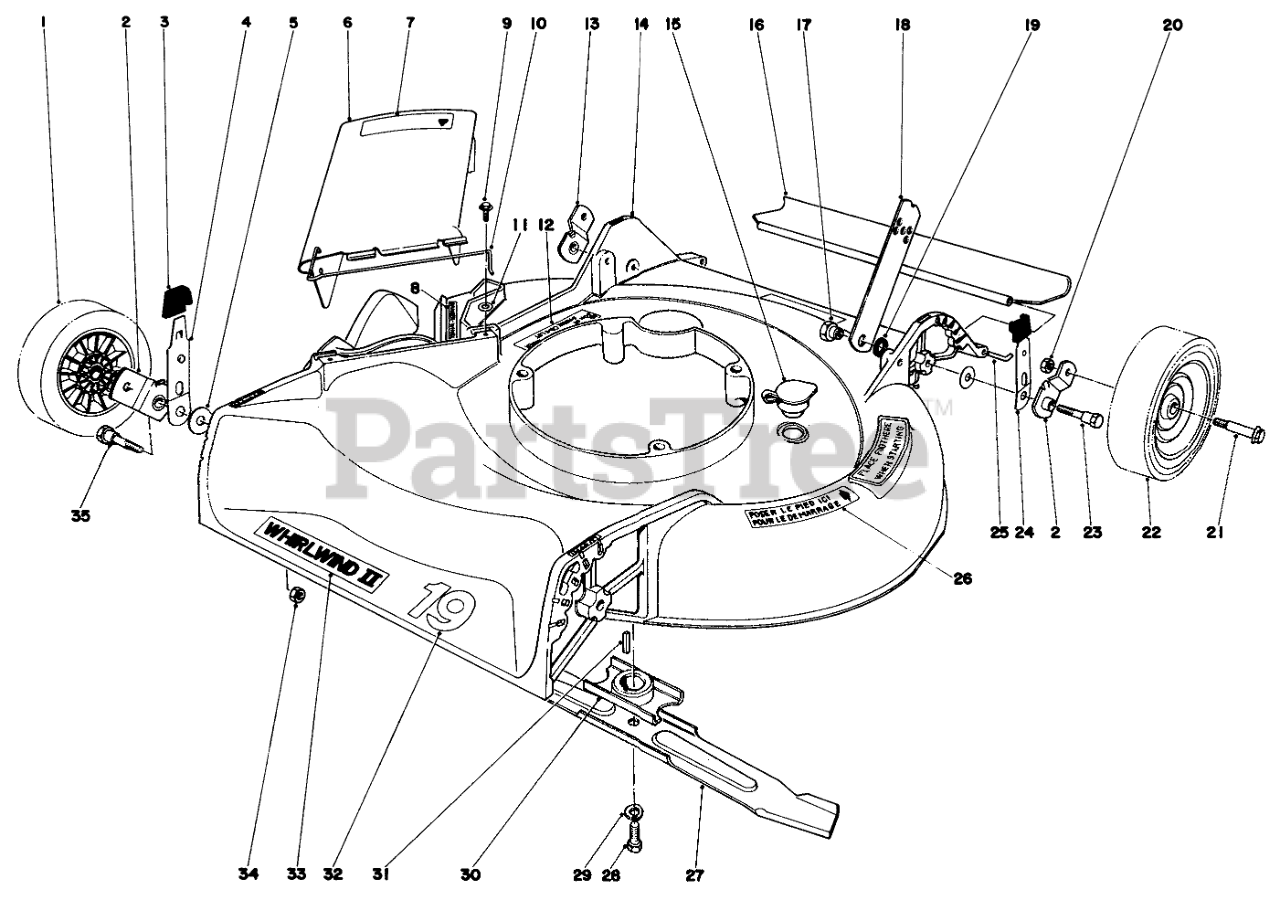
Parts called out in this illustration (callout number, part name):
1	Wheel Assembly
2	Pivot Arm
3	KNOB-ARM
4	SPRING ARM ASM
5	WASHER-PIVOT
6	Deflector-Cover Assembly (Incl. Ref. #7 & 10)
7	Decal-Caution
8	Decal-Danger
9	SCREW
10	SPRING HINGE
11	WASHER-FLAT
12	Decal-Warning
13	Pivot Arm
14	Housing (Model 16009)
15	WASHOUT PLUG
16	SHIELD - TRAILING
17	HANDLE PIVOT NUT
18	Handle Latch
19	HANDLE LATCH SPACER
20	Nut
22	Wheel Assembly
23	PIVOT SCREW
24	SPRING ARM ASM
25	SHIELD ROD
26	Decal-Step
27	Blade
28	SPECIAL SCREW
29	WASHER-LOCK
30	Blade Retailer
31	KEY-SQUARE
32	Decal-19"
33	Decal Whirlwind
34	Nut
35	PIVOT SCREW
